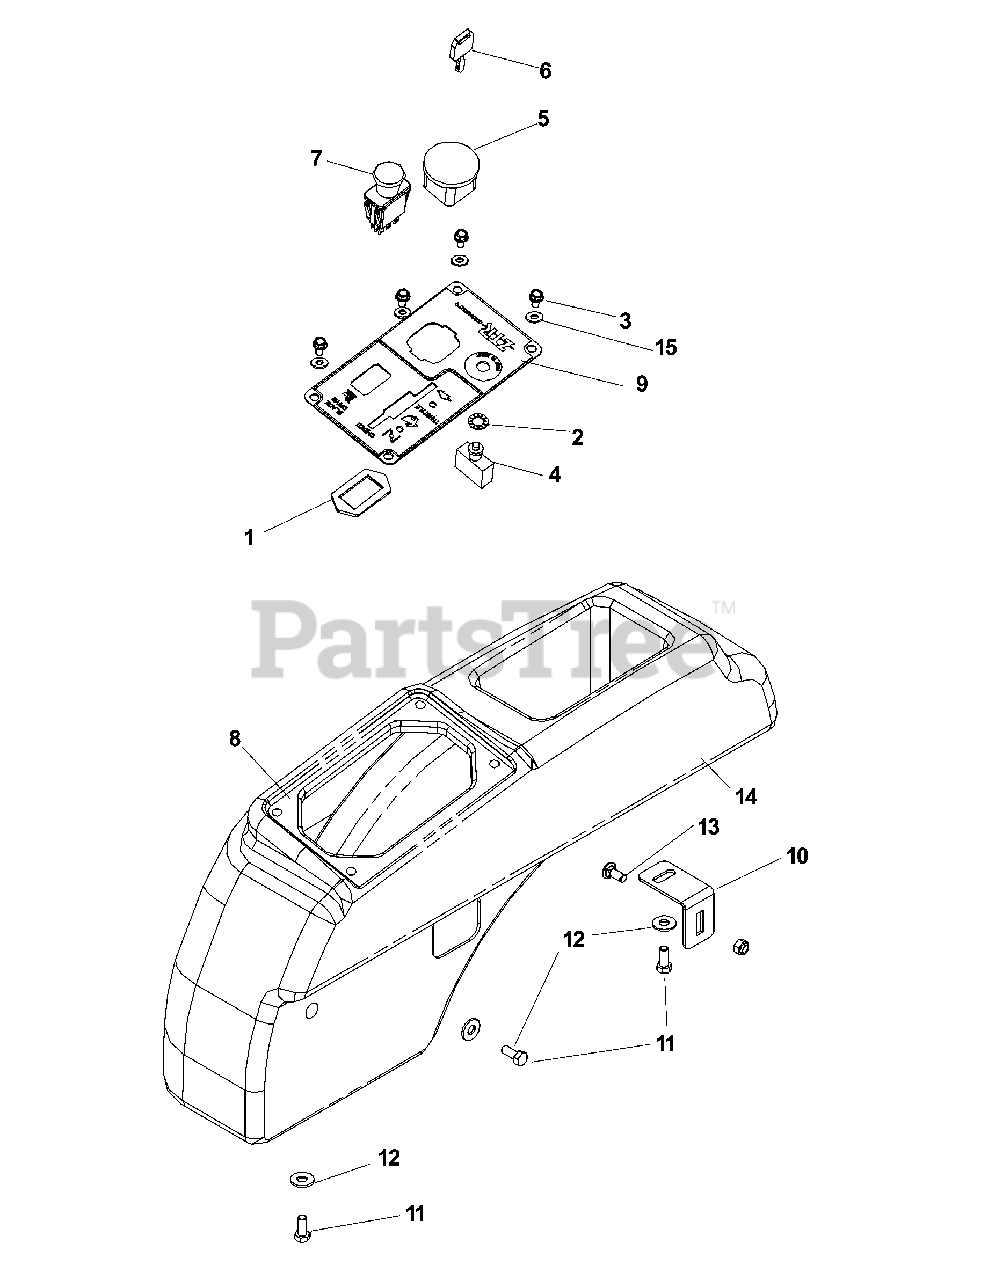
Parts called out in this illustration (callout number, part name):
1	PTO SWITCH RETAINER
2	7/16 INT TOOTH LWASH
3	SCREW 1/4 X 5/8
4	CIRCUIT BREAKER W58XB1A4A15
5	IGNITION SWITCH
6	KEY
7	SWITCH, BLADE
8	FENDER RH
9	CONTROL PANEL
10	TANK BRKT.
11	HCS 5/16C X 3/4
12	FLAT WASHER 5/16 SAE
13	BOLT 5/16C X 3/4" CARRIAGE
14	NUT 5/16 NYLOC
15	WASHER 1/4 FLAT
